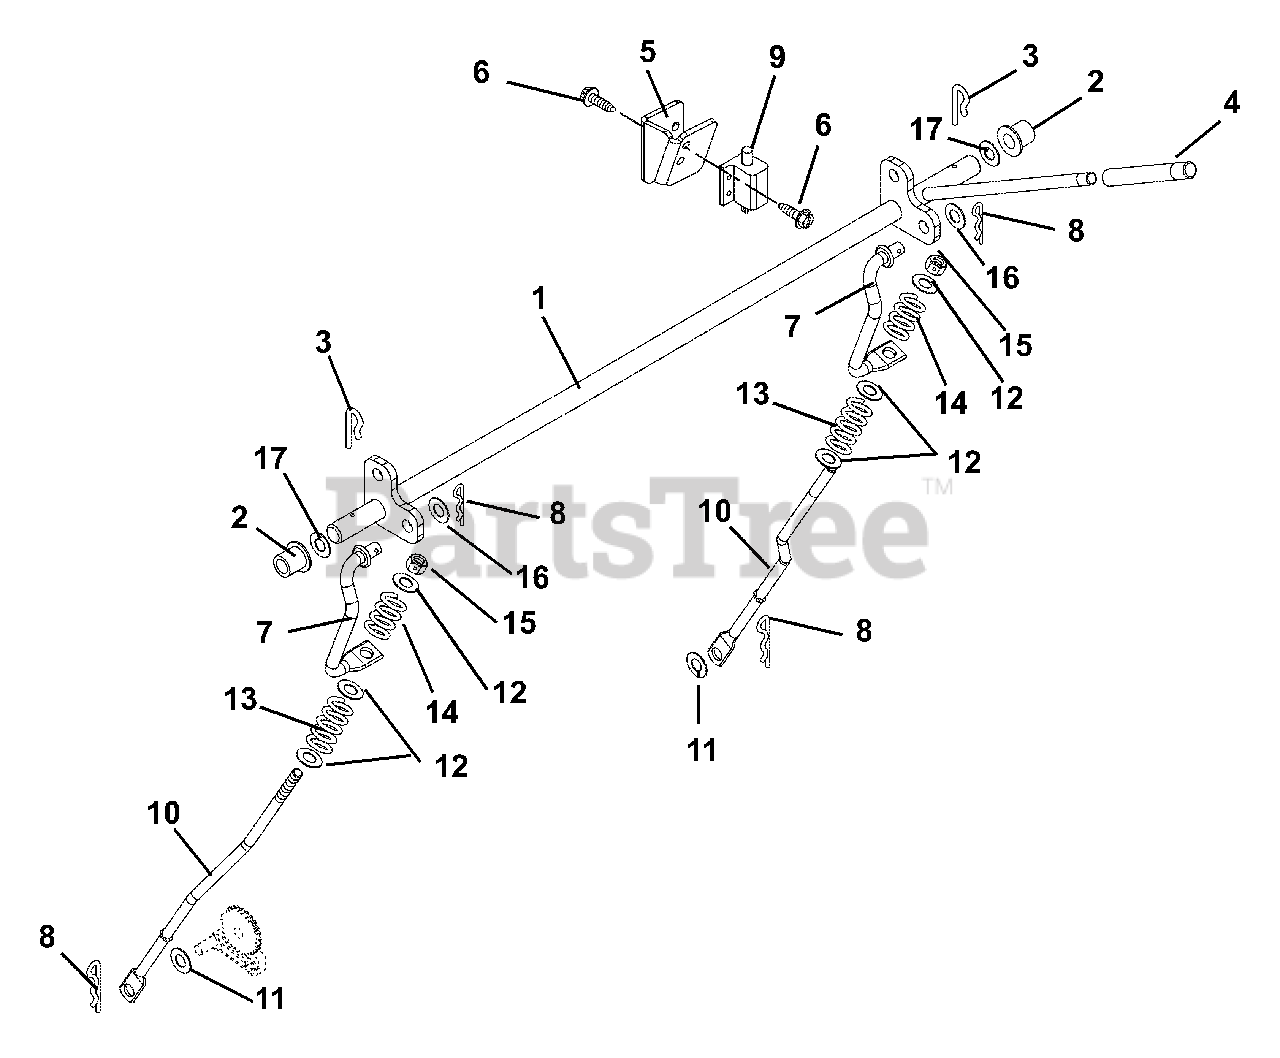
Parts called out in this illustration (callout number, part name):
1	Weldment, Zoom Brake Rod
2	Bushing, Flange .63 x 1.00 x .625 Nylon
3	Pin, Spring Clip
4	Grip, Hand Clutch Lever
5	Bracket, Brake Switch
6	Screw, Tapping 10-24 x .50 Hex Washer Head
7	Rod, Over Center
8	Pin, Hair
9	Switch, Interlock
10	Rod, Park Brake
11	Washer, Flat Steel .406 x 1.00 x .188
12	Washer, Flat Steel .344 x .688 x .065
13	Spring, Compression .045 x .50 x 1.187
14	Spring, Compression .063 x .53 x 1.187
15	Nut, Locking Nylon .312-18
16	Washer, Flat Steel .406 x .812 x .065
17	Washer, Flat Steel .627 x .99 x .032
